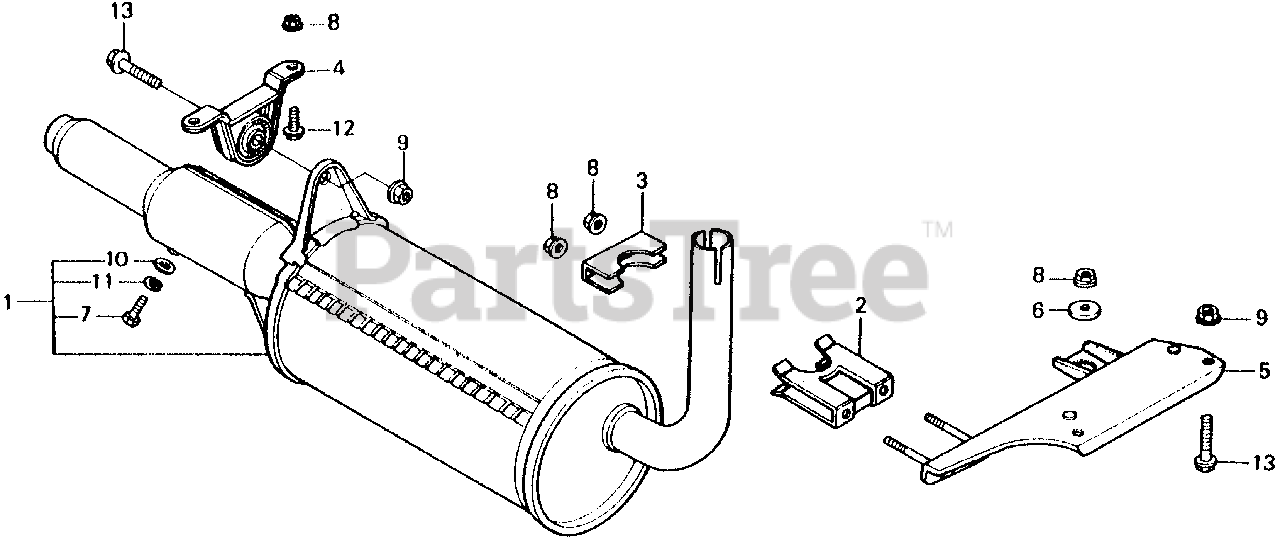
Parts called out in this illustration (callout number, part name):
1	MUFFLER ASSY. (NOT AVAILABLE)
3	STAY B, EX. PIPE
4	BRACKET ASSY., RR. MUFFLER
5	STOPPER, BUMPER (NOT AVAILABLE)
6	WASHER (8MM)
7	BOLT, HEX. (6X10)
8	NUT, FLANGE (8MM)
9	NUT, FLANGE (10MM)
10	WASHER, PLAIN (6MM)
11	WASHER, SPRING (6MM)
12	BOLT, FLANGE (8X16)
13	BOLT, FLANGE (10X50)
